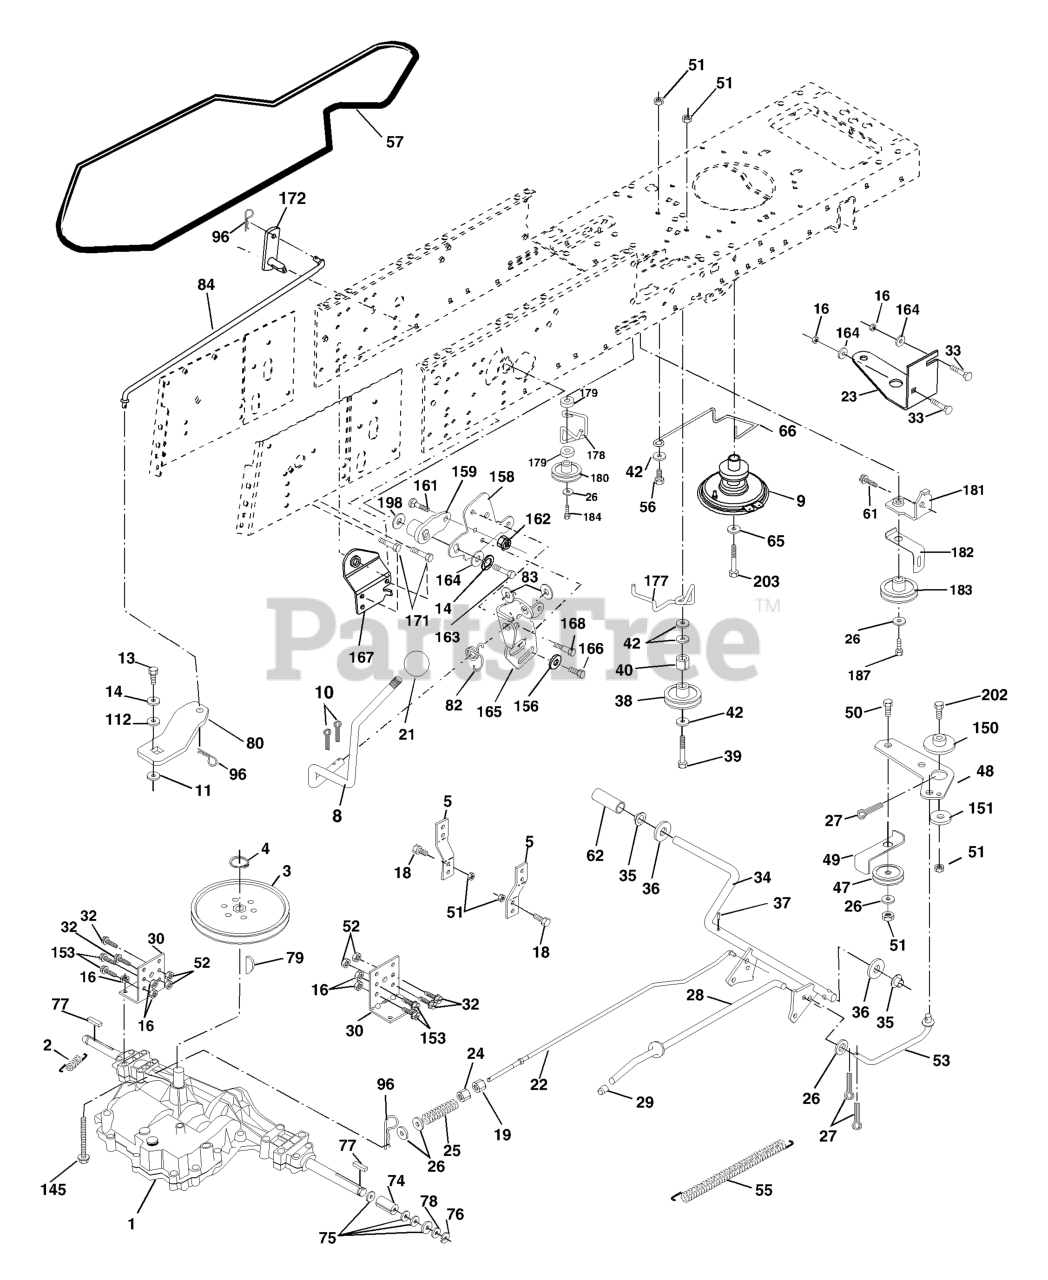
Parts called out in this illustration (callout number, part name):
2	SPRING,BRAKE RETURN
3	PULLEY
4	RETAINING RING LT
5	STRAP TORQUE
8	ROD.SHIFT.FENDER.ADJ.LT.CRD
9	CLUTCH ASSY
10	PIN COTTER
11	WASH-SHFT PLT LT
13	BOLT 1/4-28X3/4
14	LOCKWASHER
16	NUT.71038.31-18.HEX.NYLOCK
18	BOLT
19	NUT
21	KNOB.DUCKHEAD.1/2
23	Bracket Pnt Clutch Noram
24	NUT
25	SPRING ROD LT
26	WASHER
27	COTTER PIN
28	ROD BRAKE PARK LT
29	PLUNGER CAP
30	BRACKET TRANSAXLE
32	BOLT
33	Bolt Rdhd Sqnk 5/16-18 Unc x 3/4
35	BEARING.NYLON
36	WASHER LT
37	DRIVE PIN
38	PULLEY.FLAT
42	WASHER
47	IDLER PULLEY
48	BELLCRANK, CLUTCH
49	RETAIN BELT
50	BOLT
52	LOCKNUT
53	LINK, CLUTCH LT
55	SPRING, RETURN LT
57	V-BELT.KEV.111"
61	SCREW 3/8-16X3/4
62	COVER, PEDAL (1 2)
63	PULLEY, CLUTCH ELECT EVX
65	LOCKWASHER
66	KEEPER BELT ENGINE
74	SPACER AXLE
77	SQUARE KEY
79	KEY STD (1373) DANA
82	SPRING,TORSION
83	WASHER
96	RETAINER M
112	WASHER LT
145	BOLT
150	BUSHING.BELLCRANK.GRD.DR
151	WASHER 12/32X2X10GA
153	BOLT RB
156	WASHER.SRRTD.5/16
158	BRACKET
159	HUB
161	BOLT
162	NUT.CROWNLOCK.1/4
163	BOLT
164	Washer 5/8 x .281 x 10 Ga.
165	RP BRACKET
167	BRACKET.SUPT.SHIFT.CRD
168	BOLT.SHOULDER.5/16-18X
171	SCREW LT
172	SHAFT
180	PULLEY.FLAT.IDLER
181	BRKT.IDLER.GRD.DR.CRD
182	KEEPER BELT
183	PULLEY.V-IDLER
184	SCREW.HXWSH.3/8
187	SCREW
188	SNAP BUSHING T
198	WASHER.NYL.7/8IDX.105"HYD CR
202	BOLT.3/8-16X1.50
203	BOLT.HEX.7/16-20 X 5
